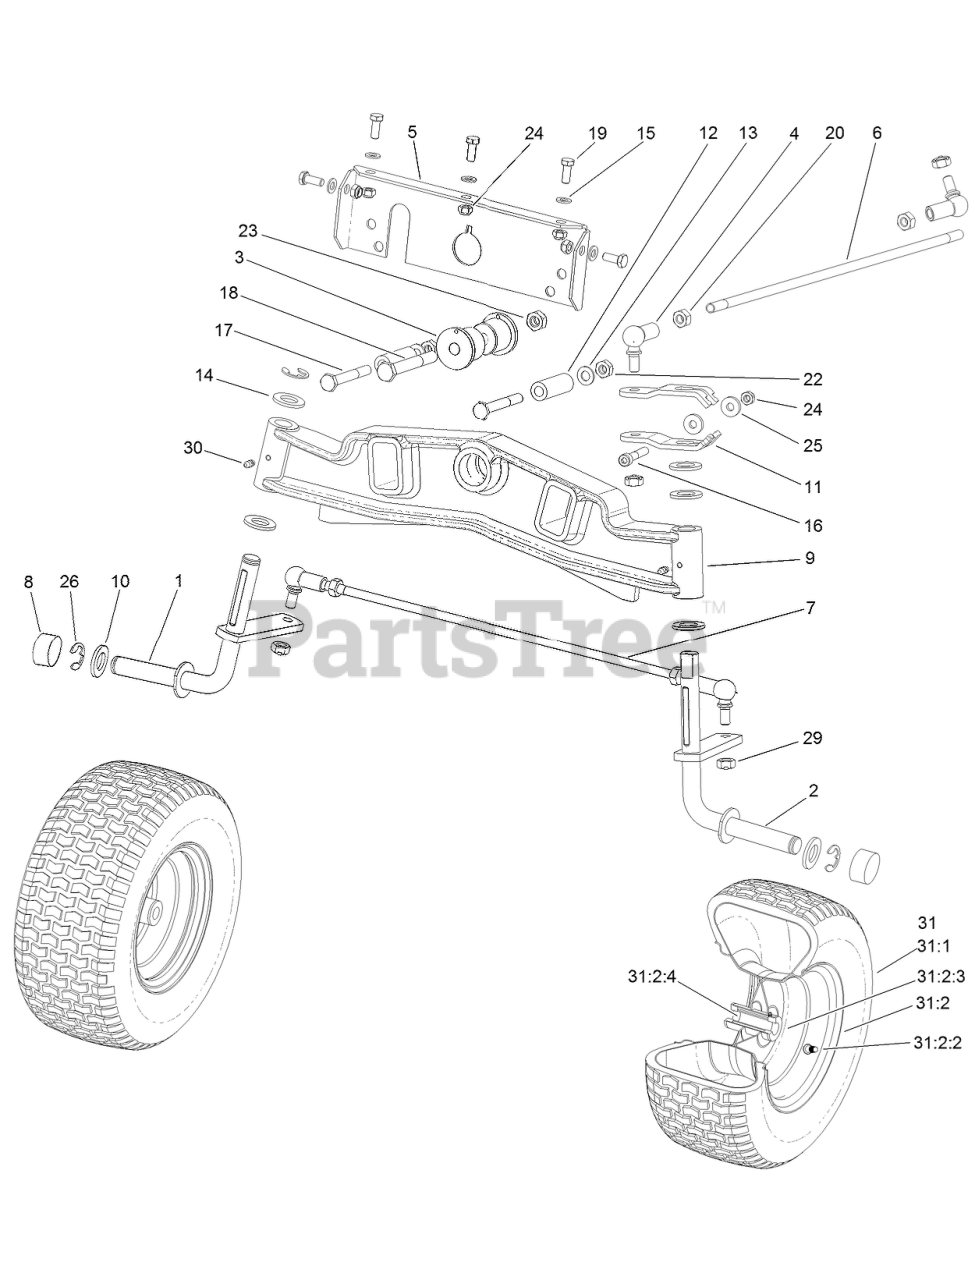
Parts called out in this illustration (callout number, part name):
1	SPINDLE-FRONT, RH
2	SPINDLE-FRONT, LH
3	BUSHING-AXLE, FRONT
4	JOINT-BALL, ANGLE
5	PLATE-AXLE
6	LINK-DRAG
7	ROD-TIE, FRONT AXLE
8	CAP-HUB
9	AXLE-FRONT
10	WASHER
11	LEVER-SPINDLE, STEERING
12	SPACER
13	WASHER-FLAT
14	WASHER-FLAT
15	WASHER-PLAIN
17	SCREW-HH
18	SCREW-HH
19	SCREW-HH
20	NUT-HEX
22	NUT-LOCK, NI
23	NUT-LOCK, HEX NI
24	NUT-LOCK, NI
25	Washer-Flat
26	CLIP-SPRING
29	Nut-Lock
30	FITTING-GREASE
31	WHEEL ASM
31:2	WHEEL ASM
31:2:2	Valve-Tire
31:2:3	BEARING-WHEEL
31:2:4	Spacer-Wheel
